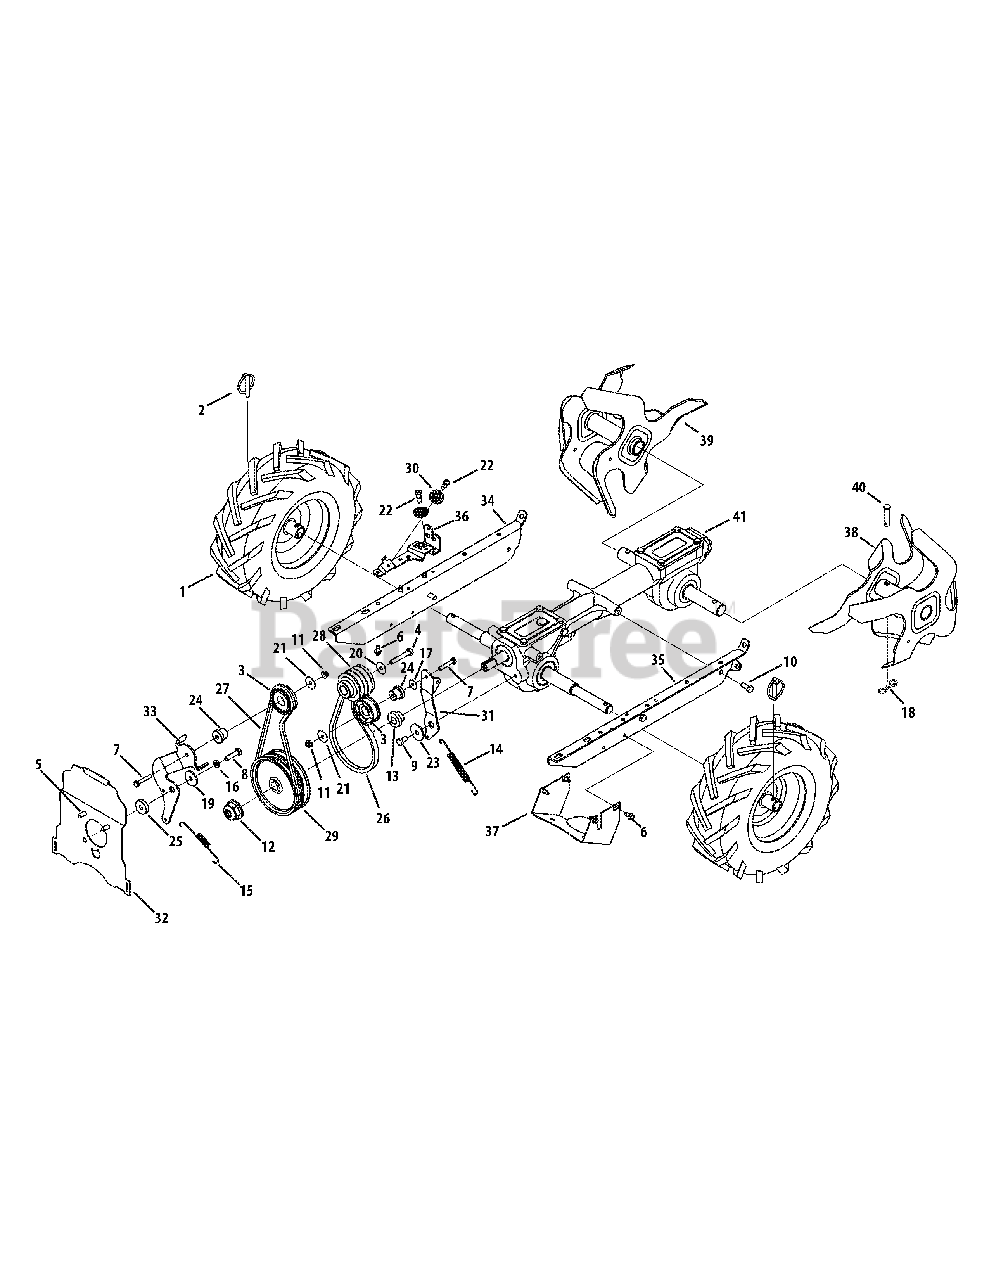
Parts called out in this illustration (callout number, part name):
1	Complete Wheel. Assy., 13 x 5 x 6 (B, C)
2	Klik Pin
3	Idler Pulley Assembly
4	Hex Head Screw, 3/8-24 x 2.00
5	Hex Head Screw, 5/16-24 x .625
6	Self Tapping Screw, 1/4-20 x .500
7	Hex Head Screw, 1/4-20 x 1.50
8	Hex Head Screw, 5/16-18 x 1.25
9	Hex Head Screw, 5/16-18 x .75, Patch
10	Hex Head Screw, 5/16-18 x .75, STD
11	Nylon Hex Lock Nut, 1/4-20
12	Nut, 9/16-18, Flange Lock
13	Hub, 5/8 Spline
14	Extension Spring, .480 OD X 5.00 LG
15	Extension Spring, 4.20 LG
16	Lock Washer, 5/16
17	Washer, .28 x .74 x .063
18	Internal Cotter Pin
19	Flat Washer, .330 X 1.25 X .120
20	Bell Washer, .396 x 1.140 x .095
21	Flat Washer, .265 x 1.0 x .030
22	Shoulder Screw, .342 x .335 1/4-28
23	Pivot Idler Spacer
24	Shoulder Spacer, .260 x .785 x .538
25	Pivot Idler Spacer
26	V-Belt, 4L x 25.375 Long
27	V-Belt, 3L x 29.125 Long
28	Engine Pulley
29	Transmission Pulley
30	Cable Roller
31	Idler Bracket, Forward
32	Cover Plate
33	Idler Bracket, Reverse
34	Mounting Frame, RH
35	Mounting Frame, LH
36	Pulley Bracket
37	Pulley Shield
38	Tine Assembly, LH
39	Tine Assembly, RH
40	Clevis Pin, .375 x 1.75
